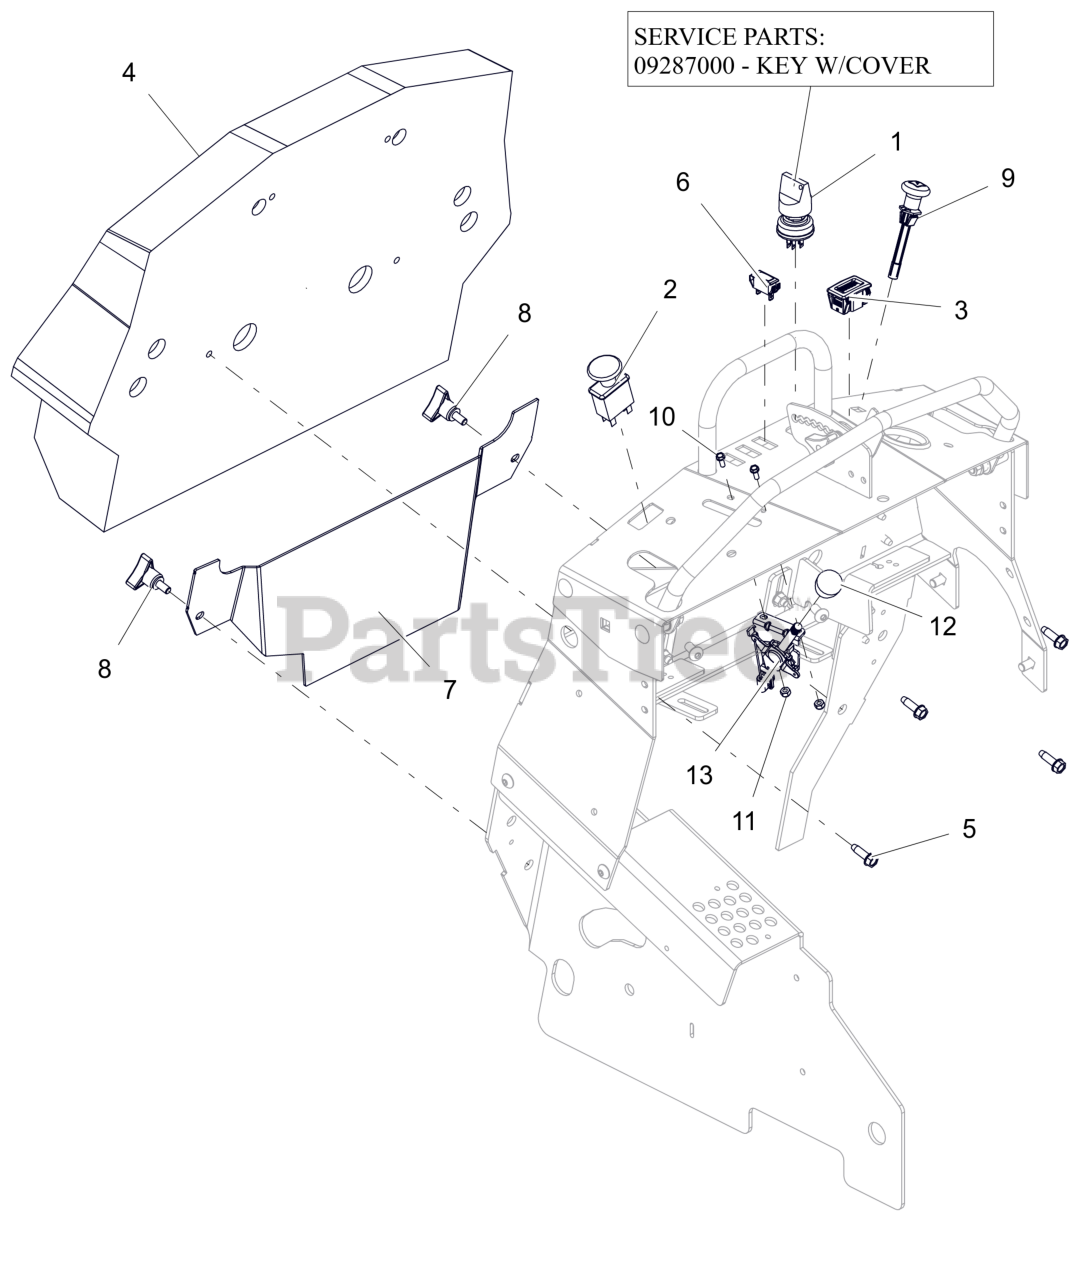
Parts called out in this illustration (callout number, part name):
1	SWITCH, IGNITION
1	KEY, W/ SHIELD
2	SWITCH, CLUTCH
3	HOUR METER
4	PAD, OPERATOR - PROSTANCE
5	SCR-TAP .312-18X1.00 HWH ZCC
6	LIGHT, INDICATOR (RED)
7	COVER, REAR TOWER (BLACK)
8	KNOB,WING STUD 5/16-18 X .75
9	CABLE, CHOKE (SNAP IN)
10	BLT, HWH #10-24X.50 ZCC
11	NUT-LK-NYL #10-24 G2 ZCC
12	KNOB-CONTROL-BLACK .38-16X.50
13	CABLE, PROSTANCE - CONTROL 43"
